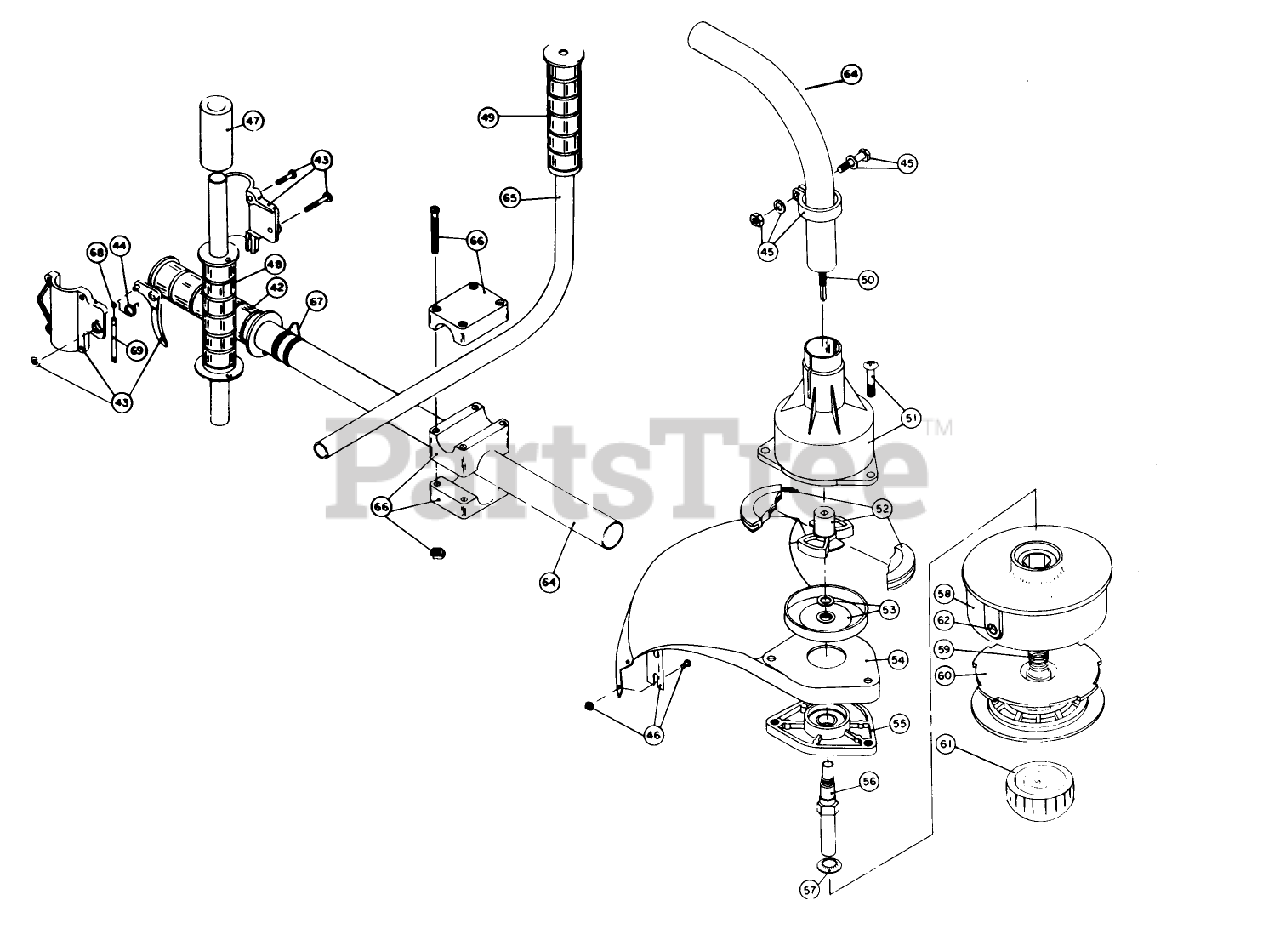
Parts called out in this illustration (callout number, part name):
44	THROTTLE TRIGGER SPRING
46	BLADE ASM
51	CLUTCH HSG ASM
